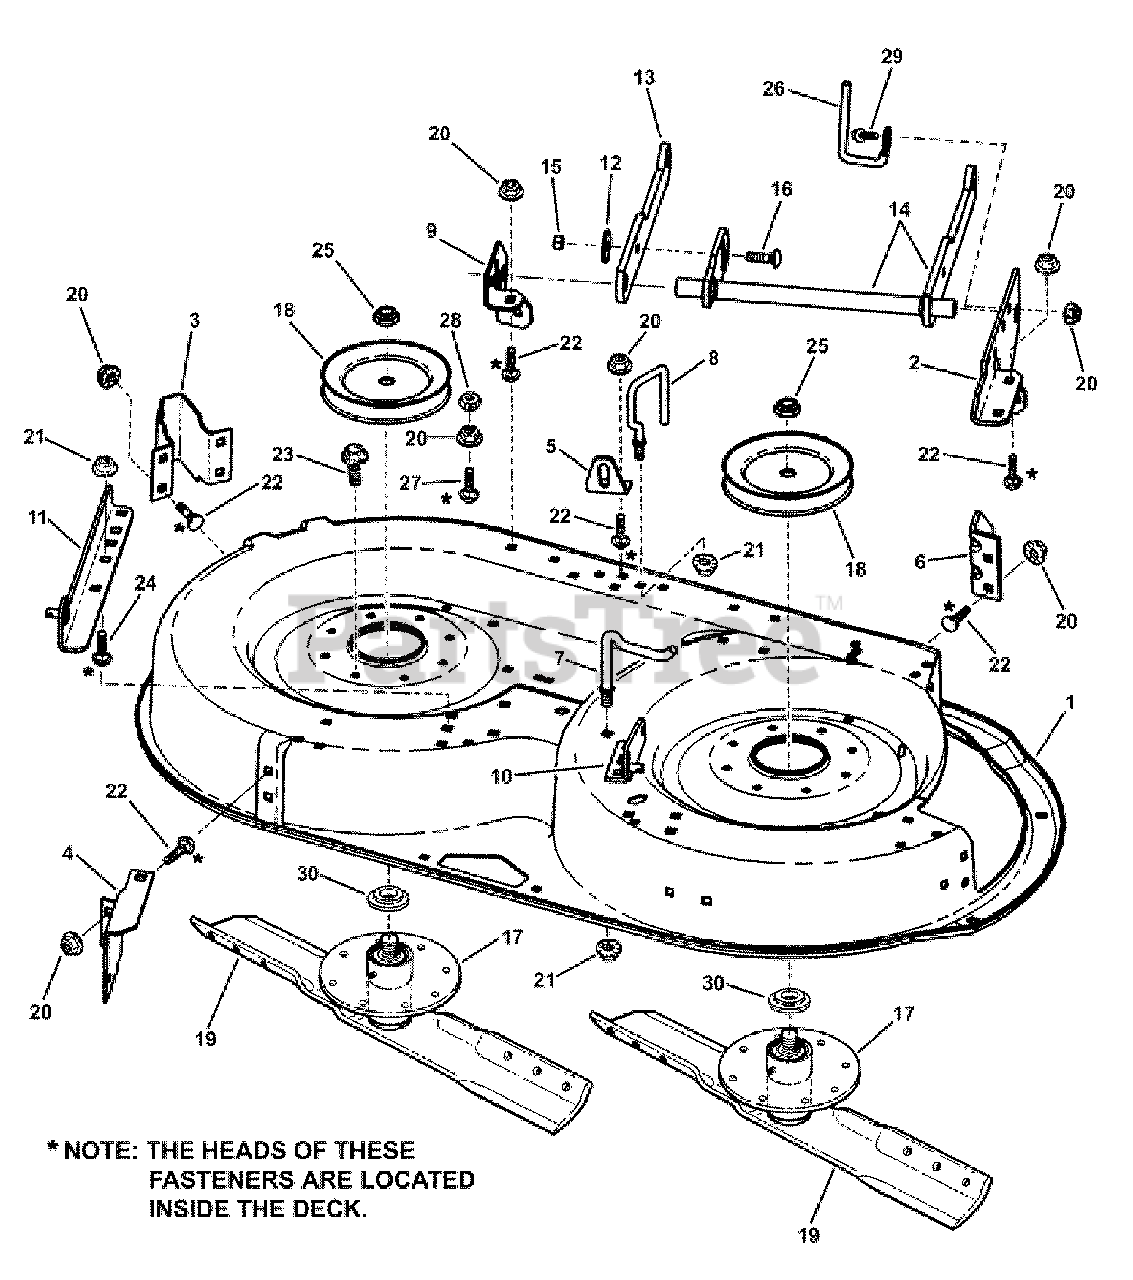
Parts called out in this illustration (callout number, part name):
1	DECK, 38"
2	BRACKET, Front Linkage
3	BRACKET, LH Front Gage Wheel
4	BRACKET, LH Rear Wheel
5	ANGLE, Front
6	BRACKET, RH Front Gage Wheel
7	CRADLE, Spring
8	GUIDE, Belt Dual Spindle Brake
9	BRACKET, Front Lift Arm - LS
10	BRACKET, Sector Lift RH Rear
11	BRACKET, Sector Lift LH Rear
12	WASHER, Cone
13	FRONT LIFT ARM, 38 Deck
14	STRUCTURE, Front Lift Arm
15	NUT, 5/16-18 Hex Center Lock
16	BOLT, 5/16-18 x 1-1/8" Short Square Neck Carriage, Grade 5
17	ASSEMBLY, 38 Spindle
18	PULLEY, Spindle
19	BLADE, 38" Cutting Deck, 19.64" Long
20	NUT, 5/16-18 Flange Lock, Grade 5
21	NUT, 3/8-16 Hex Flange Lock
22	BOLT, 5/16-18 x 5/8" Short Square Neck Carriage, Grade 5
23	BOLT, 3/8-16 x 3/4" Hex Washer Self Tap
24	BOLT, 3/8-16 x 3/4" Short Square Neck Carriage, Grade 5
25	NUT, 5/8-18 Nyloc
26	GUIDE, Belt Side Rail
27	BOLT, 5/16-18 x 1-1/8", Square Neck Carriage, Grade 5
28	NUT, 5/16-18 Hex Center lock, Grade 5
29	SCREW, 5/16-18 x 3/4" Hex Washer Self-tapping
30	SPACER, Pulley, 1.755" OD, .655" ID, .280" Thick
